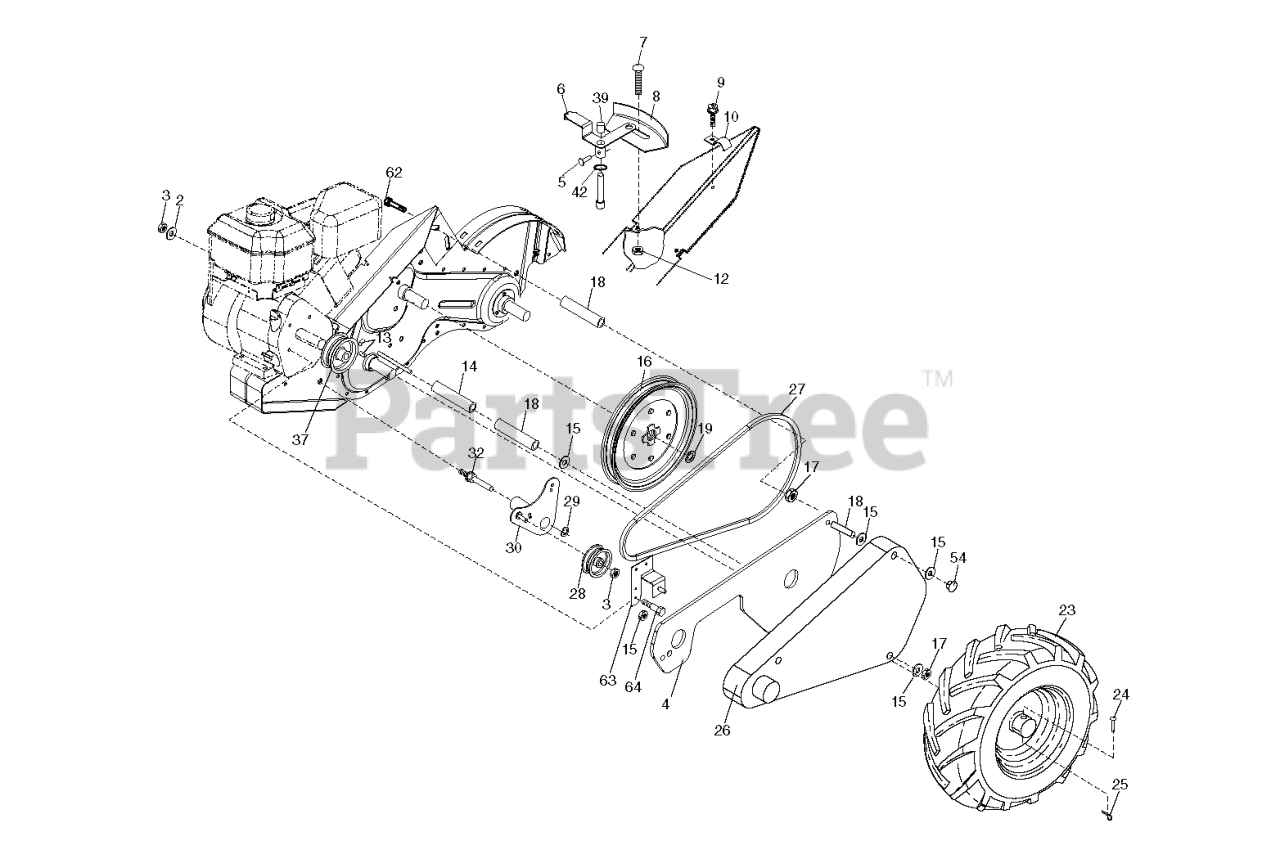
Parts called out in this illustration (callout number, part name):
2	WASHER, LOCK 3/8
3	NUT.HEX.3/8-16UNC
4	Shield, Inner Belt Guard RT
5	PIN.SPIROL.FLARED
6	LEVER ASM CRT
8	PANEL.INDICATOR.SHIFT.BLACK
9	TAPPING SCREW
10	CONDUIT.CLIP.PLATED
12	NUT
14	SPACER-SPLIT.327 X .42
15	WASHER
16	SHEAVE, TRANSMISSION
17	NUT
18	SPACER SPLIT
19	RETAINING RING LT
23	TIRE.16X4-8.CHEVRON.TILLER
25	SPRING TI
26	GUARD.BELT.TILLER.8HP.ORANGE
27	BELT, DRIVE
28	PULLEY-IDLER TI
30	BRACKET.ASM.IDLER.BLACK
32	SHAFT, IDLER ARM
37	RPSHEAVE.3.50.TILLER.ZINC.SUBA
39	CAP.PLUNGER.BLACK
62	BOLT 5/16-18X4 1/2
63	Bracket Asm Guard
